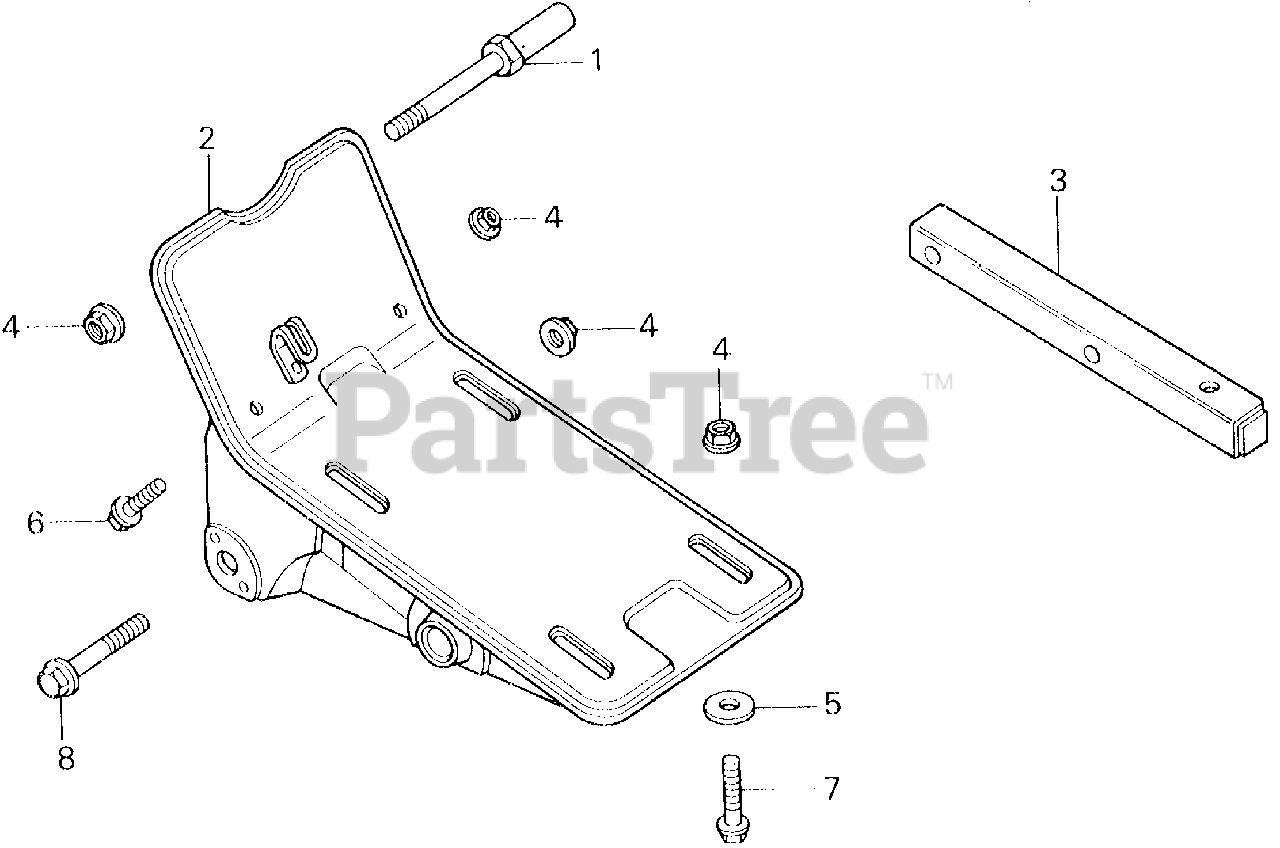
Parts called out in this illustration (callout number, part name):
1	BOLT, TENSIONER ARM
2	BED, ENGINE
2	BED, ENGINE (NOT AVAILABLE)
4	NUT, FLANGE (8MM)
5	WASHER (8X22)
6	BOLT, FLANGE (8X16)
7	BOLT, FLANGE (8X40)
8	BOLT, FLANGE (8X45)
